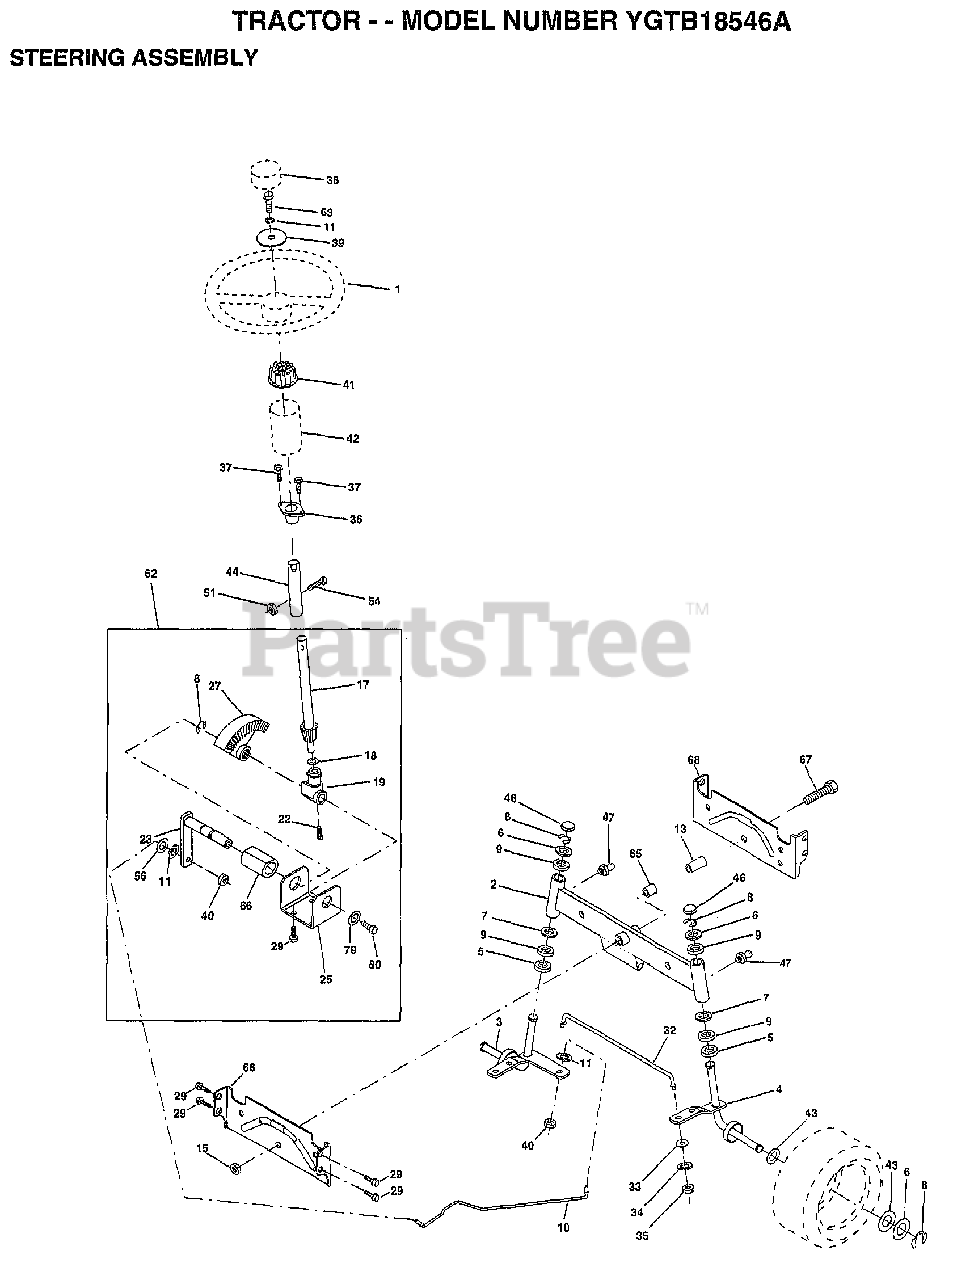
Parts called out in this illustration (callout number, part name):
1	WHEEL STR AYP BLK
2	AXLE ASM
3	"SPINDLE ASM,RH"
4	"SPINDLE AMS,LH"
5	WASHER .T
6	WASHER
8	RING
9	COL. SRTG. BEAR.
10	DRAGLINK-STAMPED
11	LOCKWASHER
13	BEARING AXLE
15	"NUT-LOC,FLANGE LT"
17	SHAFT ASM STEERIN
18	THRUST WASHER
19	SUPPORT.SHAFT.STEER
22	SCREW.HX.WSH.HD
23	SHAFT.ASM.PITMAN
25	BRKT-STEERING
27	GEAR SECTOR
29	SCREW
32	ROD.TIE.19.75
33	WASHER M
34	LOCKWASHER
35	NUT.LOCK.5/16-24
36	BUSHING.STEERING
37	"SCREW-TT,10-32 FL"
38	CAP STEER AYP
39	WASHER T
40	GRIPCO NUT
41	ADAPTER LT
42	BOOT.STEER.PL
43	WASHER
44	EXT SHAFT STEERIN
46	CAP
47	ZERK M
51	NUT
54	BOLT
56	WASHER
62	KIT.STEER.ASM
63	BOLT
65	SPACER AXLE
66	"BEARING-ARM,PITMA"
67	BOLT
68	BRACE AXLE
74	JOINT ASM BALL
75	JOINT ASM BALL
77	NUT
78	NUT
79	WASHER
80	BOLT.HX.NYLON3/8-16X3/
